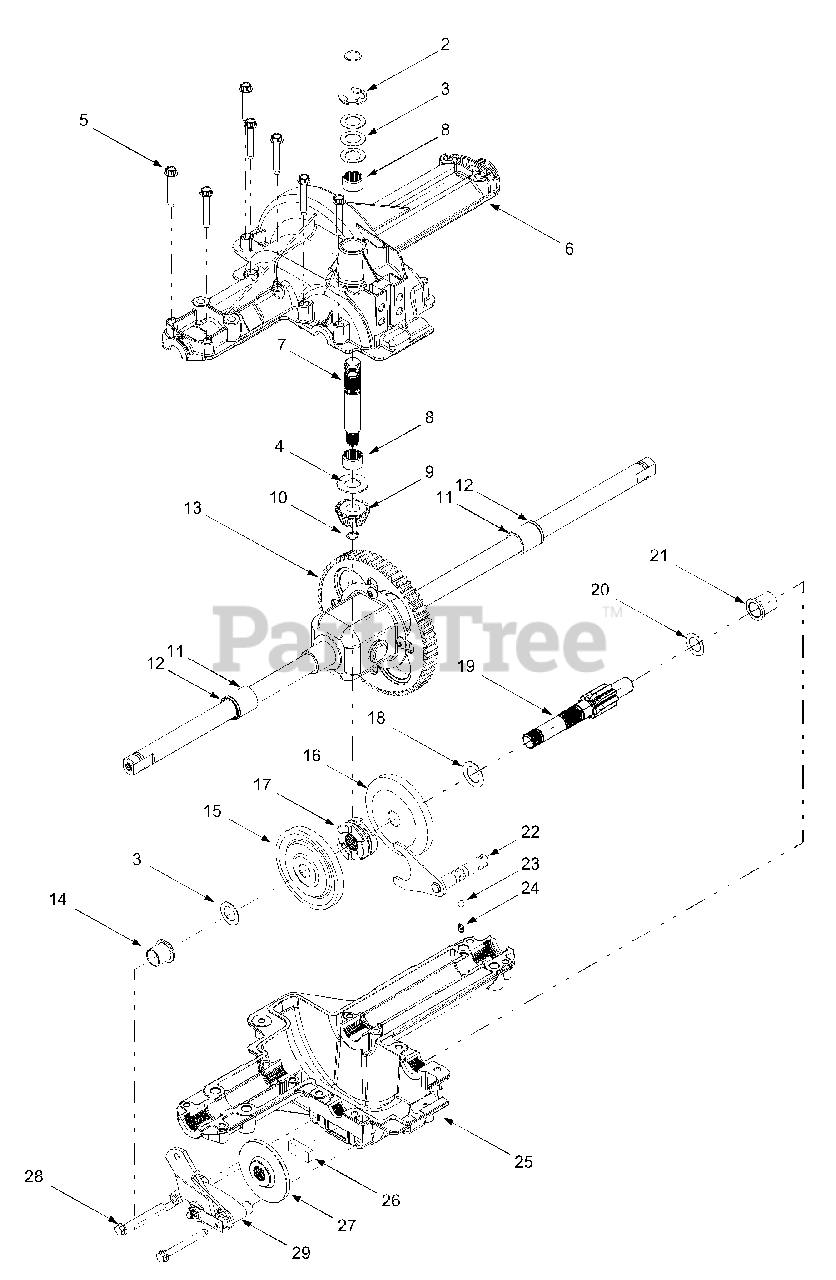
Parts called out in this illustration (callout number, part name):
1	Ring, Wire
2	Ring, E Type, .750
3	Flat Washer, 5/8 x 1.0 x .030
4	Washer, Thrust .635 x 1.26 x .06
5	Self-tapping Screw, 1/4-20 x 1.625
6	Upper Housing
7	Input Shaft
8	Needle Bearing, .625 x .813 x .495
9	14-tooth Bevel Pinion
10	Retaining Ring, .437
11	Sleeve Bearing, .75 x .1.0 x 1.0
12	Seal, .75 x 1.0 x .125
13	Differential Assembly
14	Flange Bearing, 5/8 x 3/4 x 3/4
15	42-tooth Bevel Gear
16	42-tooth Bevel Gear
17	Clutch Collar
18	Flat Washer, .70 x 1.125 x .031
19	Drive Shaft
20	Thrust Washer, 1.0 x .632 x .0
21	Flange Bearing, 5/8 x 3/4 x 15/16
22	Detent Shaft Assembly
23	Detent Ball
24	Compression Spring
25	Lower Housing
26	Brake Puck
27	Brake Disc
28	Self-tapping Screw, 1/4-20 x 2.375
29	Brake Assembly
